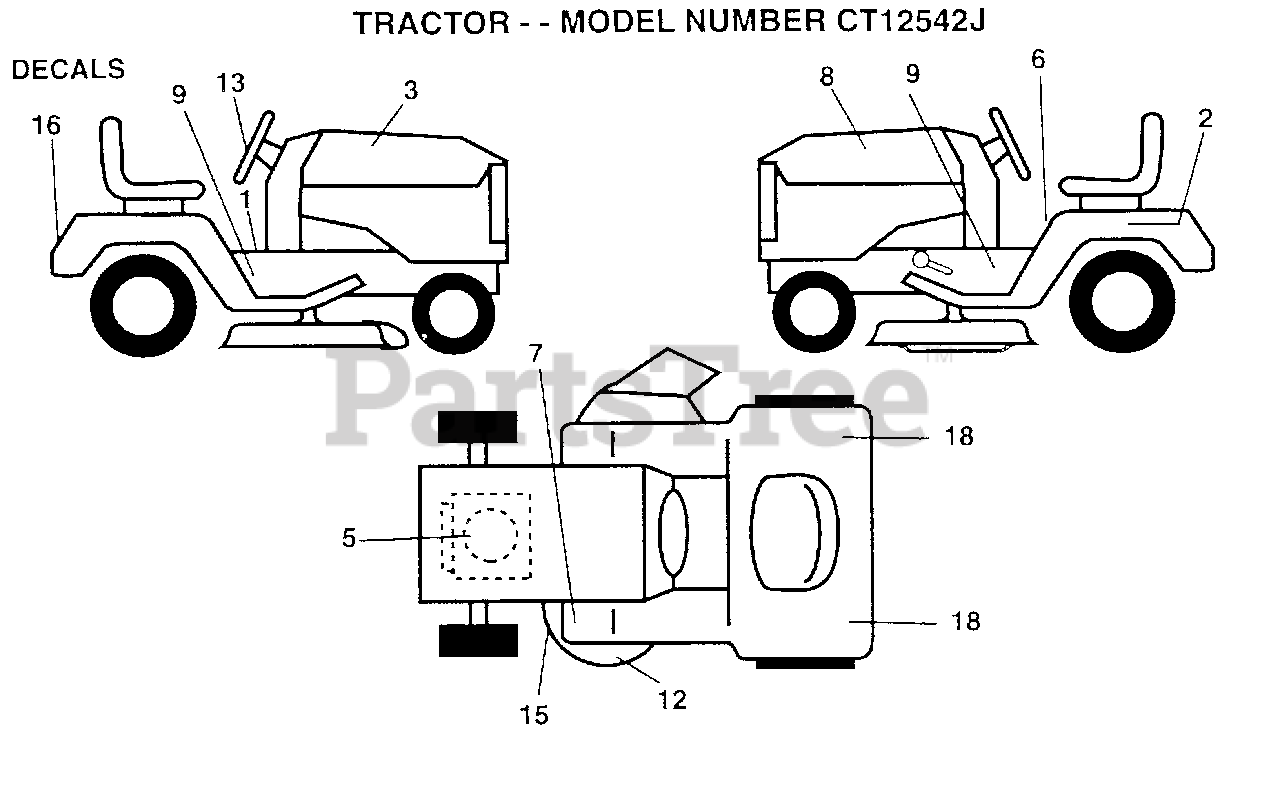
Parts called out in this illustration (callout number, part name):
2	DECAL.BTRY.DANGER
3	DECAL.HD.RH.12.5
5	DECAL, HP ENGINE
6	DECAL
8	DECAL.HD.LH.12.5
9	DECAL.CHAS.42.RAL
13	DECAL.WHL.STR.RLY
15	DECAL
16	DECAL.FEND.RALLY
18	REFLECTOR-TAIL YT
